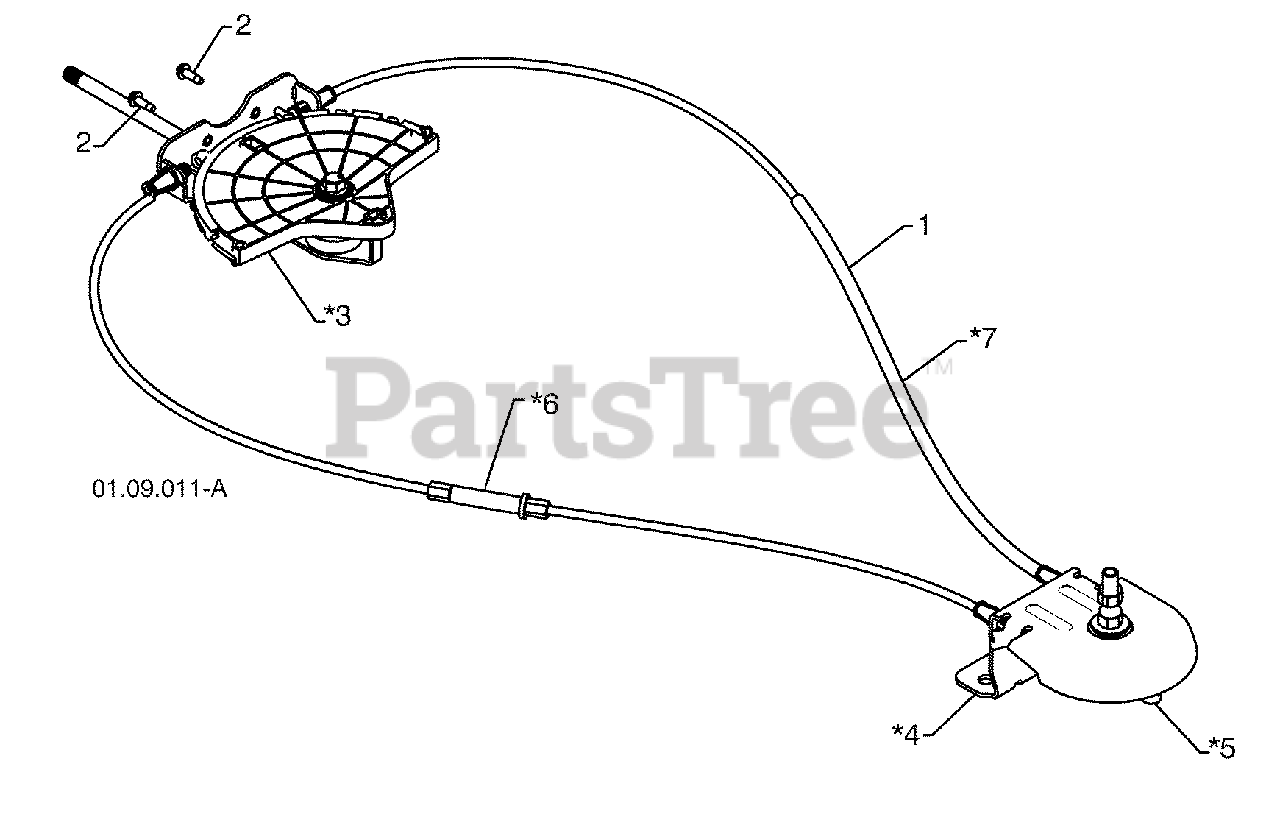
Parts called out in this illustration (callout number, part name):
1	LEVER/CABLE ROTATOR ASSEMBLY
2	SCREW 10-24 X .625
3	ROTATOR HEAD
4	ROTATOR PIVOT BRACKET
5	PULLEY PIVOT
6	CABLE ASSEMBLY ADJUSTABLE GRAY
7	CABLE ASSEMBLY HEAT SHIELD GRAY
